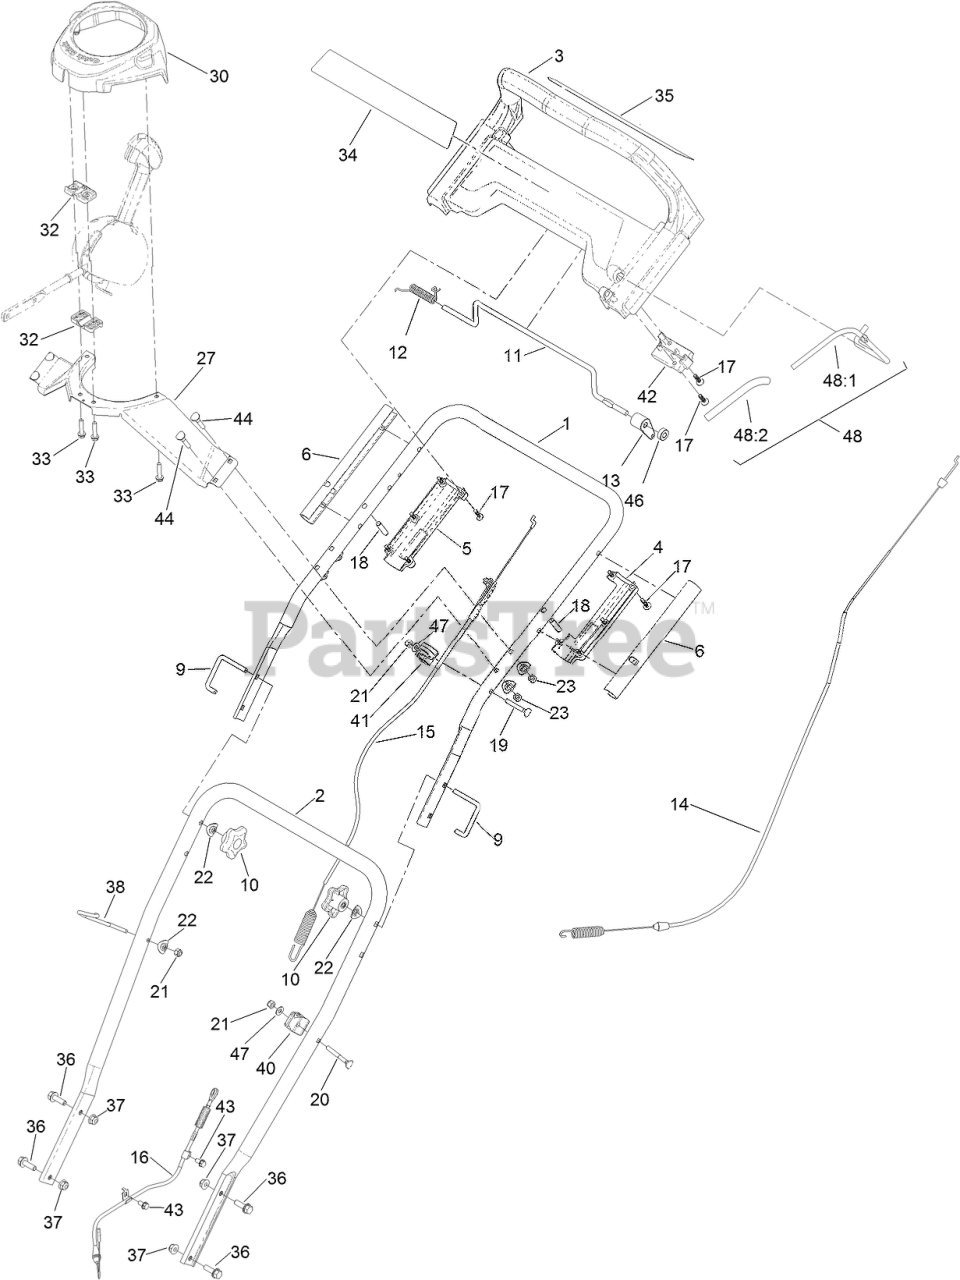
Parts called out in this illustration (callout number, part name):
1	HANDLE-UPPER
2	HANDLE-LOWER
3	HANDLE
4	HANDLE-BOTTOM, LH
5	HANDLE-BOTTOM, RH
6	SLEEVE HANDLE
9	LOCK-HANDLE
10	KNOB-HANDLE
11	BAR-CONTROL, TRACTION
12	Spring-Torsion
13	LEVER-TRACTION
14	CABLE-TRANSMISSION
15	CABLE-ROTOR, UPPER
16	CABLE-ROTOR, LOWER
18	PIN-DOWEL
19	SCREW
20	SCREW-HANDLE
21	NUT-LOCK, NI
22	WASHER
23	NUT-LOCK, NI
27	BRACKET-CHUTE, CONTROL
30	COVER TOP
32	SUPPORT-ROD
33	SCREW-PLASTITE
34	DECAL-DISPLAY
35	DECAL-CONTROL, PANEL
36	SCREW-HHF
37	NUT-HF, NI
38	GUIDE-ROPE
40	ANCHOR-CABLE, UPPER
41	CABLE-GUIDE
42	BAIL-MOUNT
43	SCREW-HWH
44	SCREW-HANDLE
46	SPACER
47	WASHER-FLAT
48	BAIL ASM
48:1	BAIL-AUGER
48:2	COVER-BAIL
